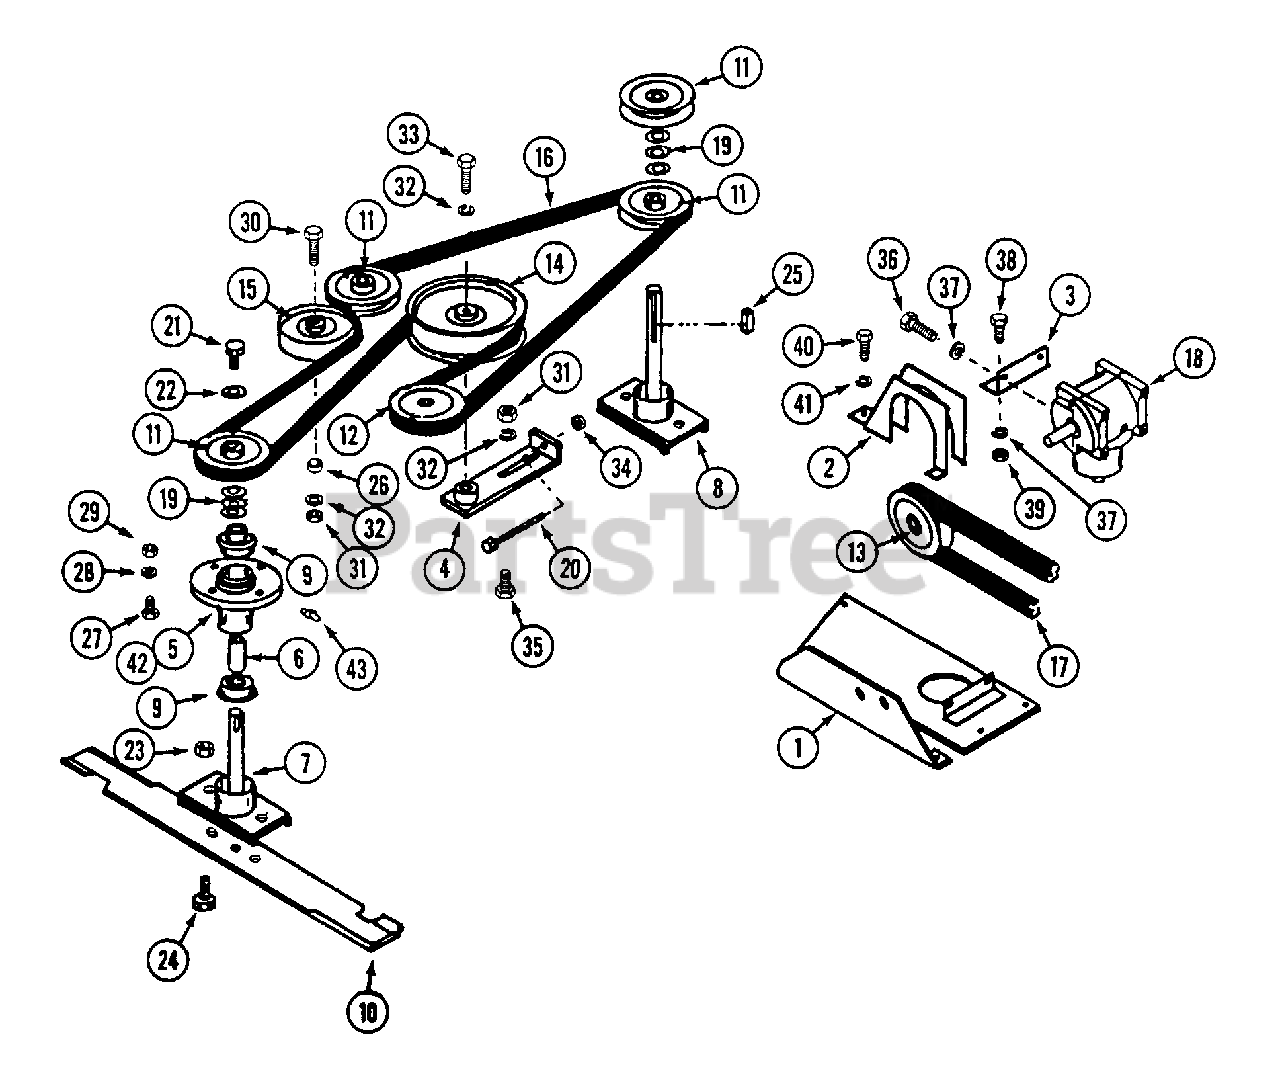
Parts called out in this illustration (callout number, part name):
1	MOUNT - gear box
2	GUARD - belt
3	ANGLE - gear box mount
4	TIGHTENER - belt
5	HOUSING - spindle
6	SPACER - spindle
7	SHAFT - spindle
8	SHAFT - spindle, long
9	BEARING - spindle
9	BEARING - spindle 7/8"
10	BLADE - mower
11	PULLEY - spindle
12	PULLEY - gear box output
13	PULLEY - gear box input
14	PULLEY - idler, large
15	PULLEY - idler, small
18	GEAR BOX - angle drive
19	SPACER - washer
20	BOLT - 1/4" - 20 x 4"
21	BOLT - 3/8" - 24 x 1-1/4"
22	WASHER - spindle
23	NUT - 3/8" - 16 lock
24	BOLT- 3/8" - 16 x 1"
25	KEY - 3/16" x 1"
26	SPACER - idler pulley
27	BOLT - 7/16" - 14 x 1-1/4"
28	LOCKWASHER - 7/16"
29	NUT - 7/16" - 14
30	BOLT - 3/8" - 16 x 2-1/2"
31	NUT - 3/8"
32	LOCKWASHER - 3/8"
33	BOLT - 3/8" - 16 x 1-1/4"
34	NUT - 1/4" - 20 lock
35	BOLT - 3/8" - 16 x 1" carriage
36	BOLT - 5/16" - 18 x 1"
37	LOCKWASHER - 5/16"
38	BOLT - 5/16" - 18 x 3/4"
39	NUT - 5/16" - 18
40	BOLT - 1/4" - 20 x 1/2"
41	LOCKWASHER - 1/4"
42	HOUSING ASSEMBLY - spindle
43	FITTING - grease 1/4" - 28
